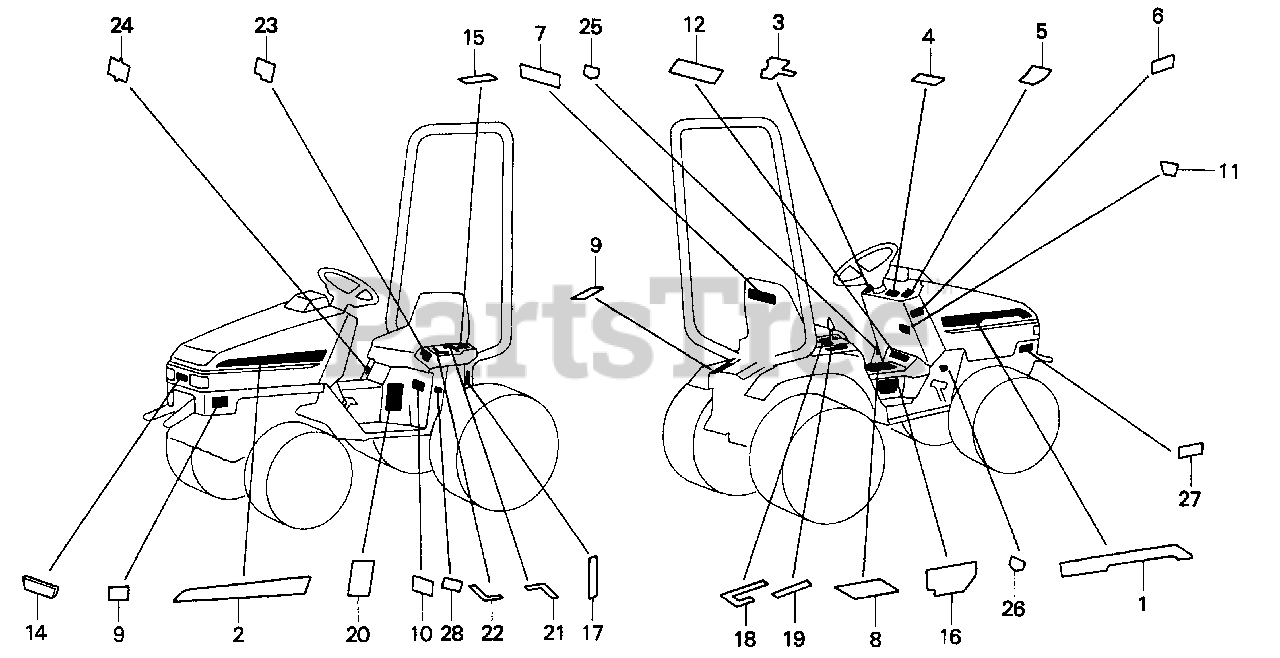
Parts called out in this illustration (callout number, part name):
1	MARK, R. SIDE STRIPE
2	MARK, L. SIDE STRIPE (4WD,4WS)
3	MARK, LIGHT OPERATION (ENGLISH)
4	MARK, ENGINE SWITCH (ENGLISH)
5	MARK, THROTTLE OPERATION (ENGLISH)
6	MARK, P.T.O. INDICATION
7	MARK, SEAT
8	LABEL, WARNING (ENGLISH)
9	LABEL B, WARNING (ENGLISH)
10	LABEL, FUEL WARNING (B)(ENGLISH)
11	MARK, BRAKE LOCK INDICATION (ENGLISH)
12	LABEL, PARKING BRAKE (ENGLISH)
14	EMBLEM, HOOD
15	MARK, P.T.O. INDICATION (ENGLISH)
16	LABEL, DIFFERENTIAL CAUTION (ENGLISH)
17	LABEL, ROLL OVER PROTECTIVE STRUCTURE WARNING (ENGLISH)
18	MARK, LIFT INDICATION (ENGLISH)
19	LABEL, HYDRAULIC ADJUST OPERATION (ENGLISH)
20	MARK, RECOMMENDED WORK SPEED (ENGLISH)
21	MARK A, MAIN CHANGE INDICATION (ENGLISH)
22	MARK B, MAIN CHANGE INDICATION (ENGLISH)
23	MARK, SUB-CHANGE INDICATION (ENGLISH)
24	MARK, CHANGE INDICATION (2/4WD)
25	MARK, CLUTCH INDICATION (ENGLISH)
26	MARK, BRAKE INDICATION (ENGLISH)
27	MARK, EX. CAUTION (A)
